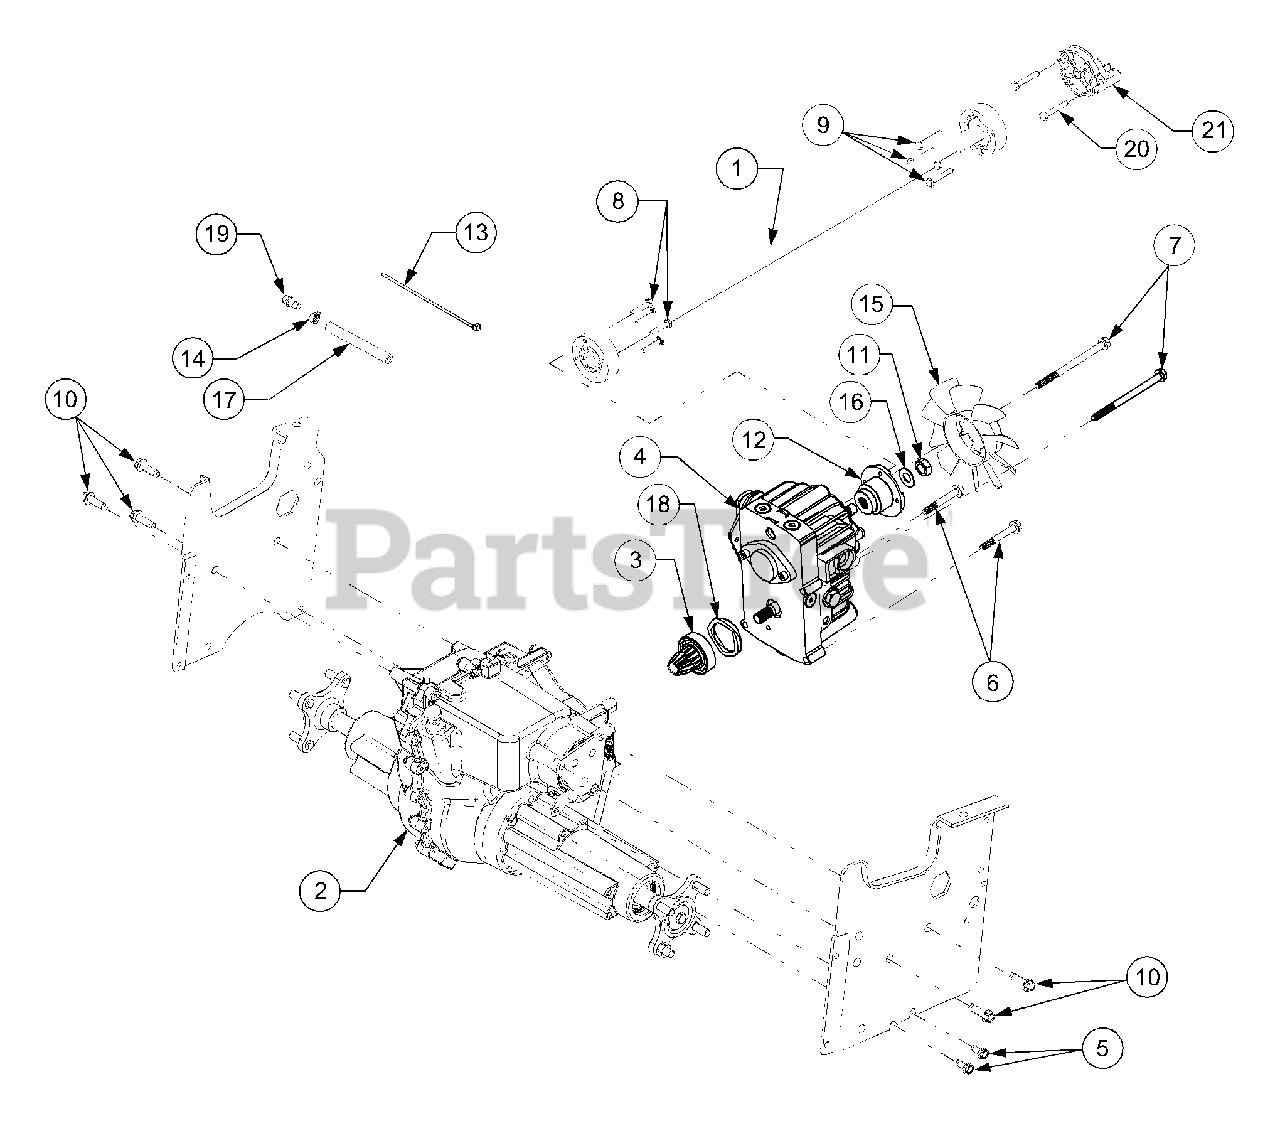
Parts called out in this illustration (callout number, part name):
1	Shaft Assembly, Drive, 28.25 Lg
2	Transmission Assembly,
3	Pinion Assembly, Input
4	Pump, Hydrostatic
5	Screw, Hex Wsh Tap, 5/16-18 x .75
6	Screw, Hex Cap, 5/16-18 x 1.75 GR5
7	Screw, Hex Cap, 5/16-18 x 4.5 GR5
8	Screw, Hex Patch, 1/4-20 x 1.25 GR5
9	Screw, Hex Patch, 1/4-20 x 1.62 GR5
10	Screw, Hex Wsh Tap, 3/8-16 x 1.25
11	Nut, Hex Top Lock Jam GR5, 1/2-20
12	Adapter, Pump
13	Tie, Self-Clinch Cable
14	Clamp, Hose
15	Fan, 10 Blade Cooling
16	Washer, Bell, 1/2 ID
17	Line, Fuel, 7in (10ft Bulk)
18	Washer, Wave, 1.96 x 2.44 x .06
20	Screw, Hex Patch, M10-1.50x 90mm
21	Adapter, Drive Shaft
